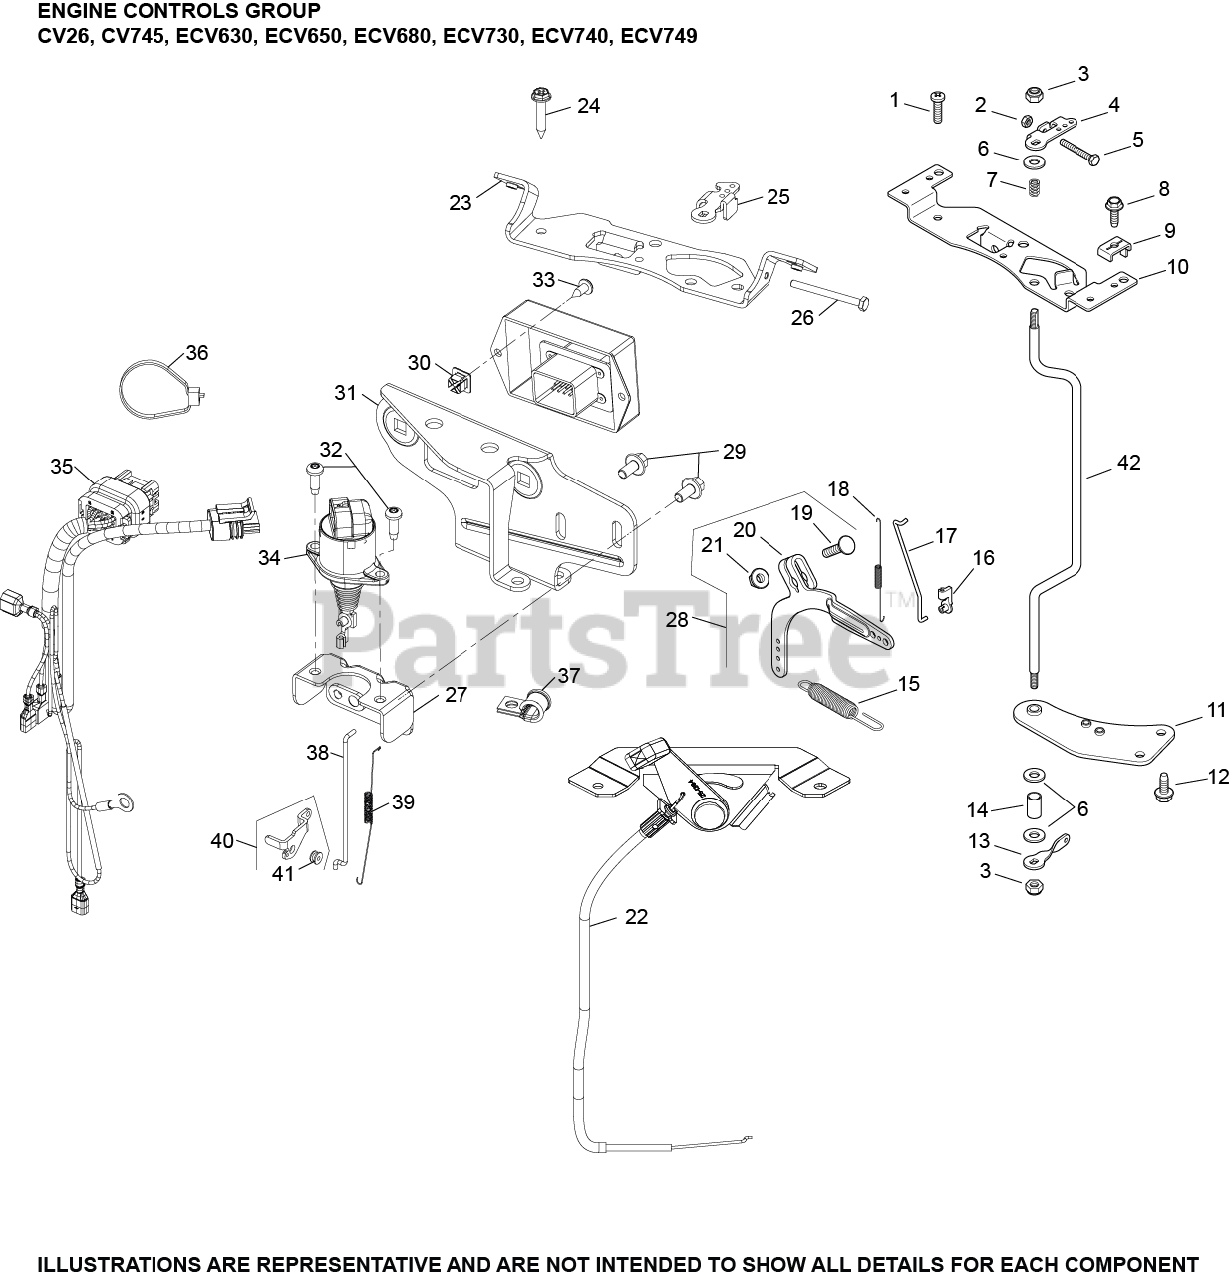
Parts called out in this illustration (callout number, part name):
2	NUT, M4X0.7
3	NUT, LOCK M6X1.0
4	LEVER, THROTTLE CONTROL
5	SCREW, CAP M4X.7X30
6	WASHER, FLAT 1/4"
7	SPRING, THROTTLE SHAFT
8	SCREW, MATHREAD M5 X 0.8 X 16
9	CLAMP, CABLE
10	BRACKET, CONTROL
11	BRACKET, THROTTLE SHAFT
12	SCREW, THREAD FORMING
13	LEVER, THROTTLE CONTROL
15	SPRING, GOVERNOR (GREEN)
16	BUSHING, THROTTLE LINKAGE
17	LINKAGE, THROTTLE
18	SPRING, LINKAGE
19	BOLT, RD HD SQ NECK M6X1.0X25
20	LEVER, GOVERNOR ASSEMBLY
21	NUT, FLG M6X1.0
42	THROTTLE CONTROL SHAFT
